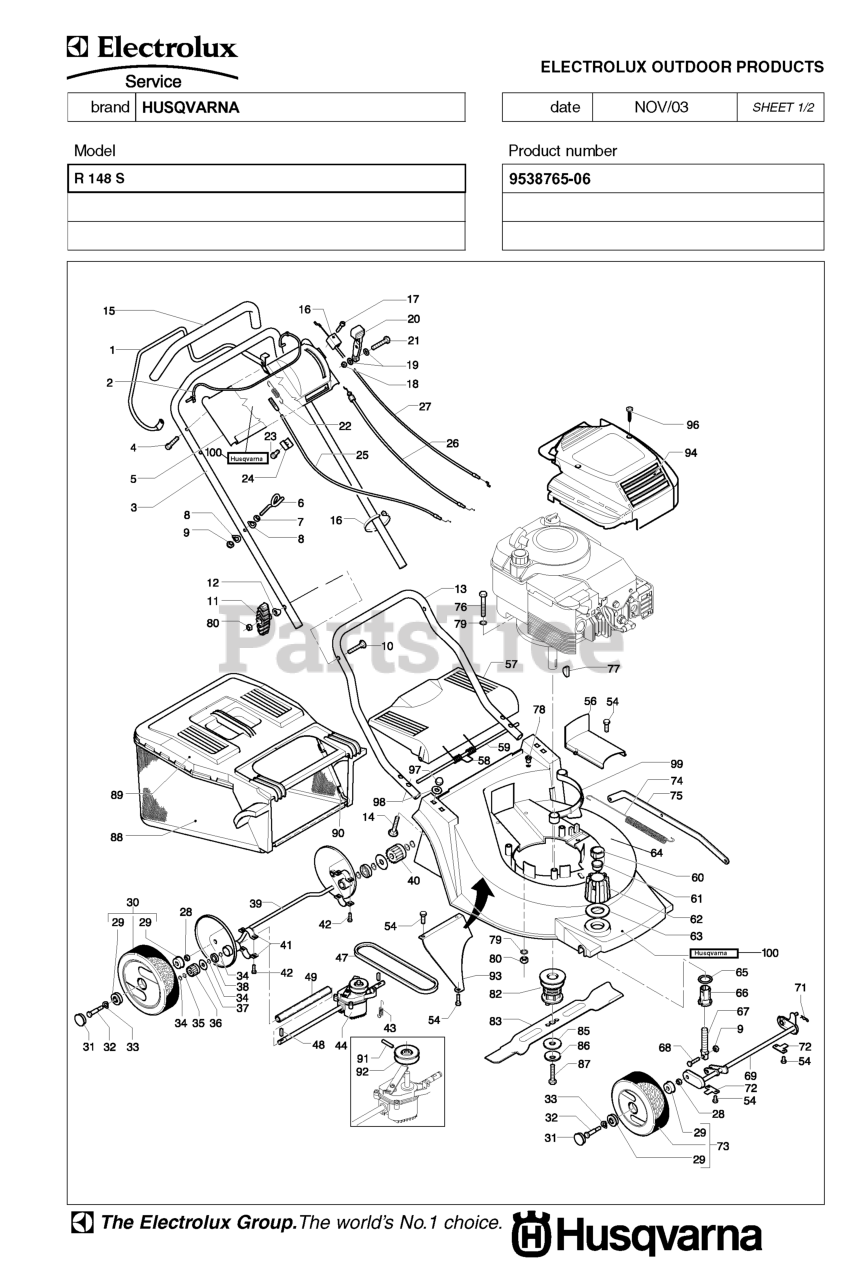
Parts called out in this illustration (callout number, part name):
34	Washers
42	SCREW
54	Screws
71	Pins
